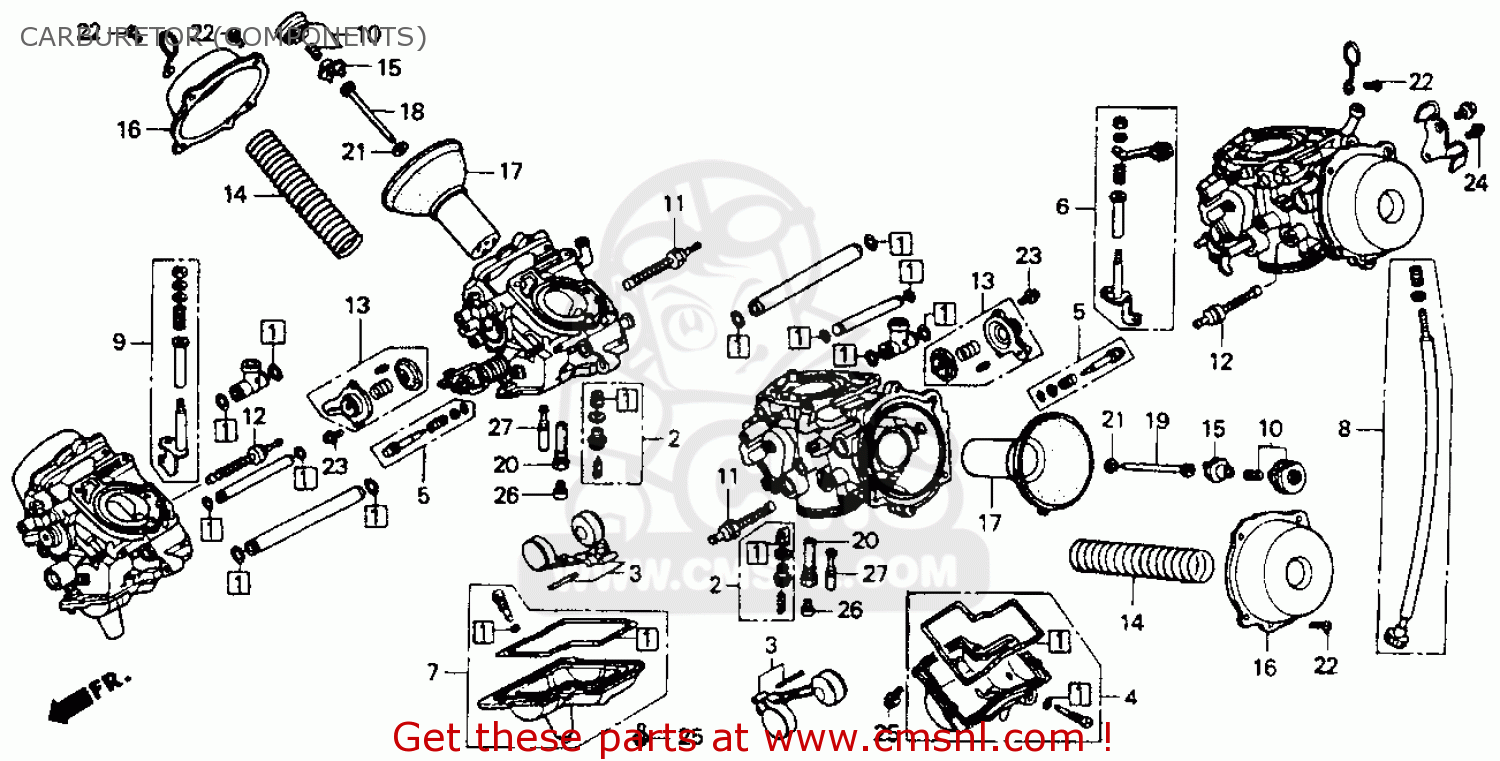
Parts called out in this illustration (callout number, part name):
1	GASKET KIT
2	FLOAT VALVE SET
3	FLOAT SET
4	FROAT CHAMBER SET
5	SCREW SET,A
6	STARTER LINK SET,
7	FROAT CHAMBER SET
8	SCREW SET,B
9	LINK SET B,STERTE
10	PLATE SET
11	VALVE SET,STARTER
12	VALVE SET,STARTER
13	VALVE SET,AIR CUT
14	SPG,VACUUM PISTON
15	COLLAR SET
16	TOP
17	PISTON COMP,VACUU
18	NEEDLE COMP,JET
19	NEEDLE COMP,JET
20	JET HOLDER,NEEDLE
21	WASHER,PLAIN
22	SCREW,PAN,4X10
23	SCREW-WASHER,4X8
26	JET,#125
27	JET,SLOW,#38
